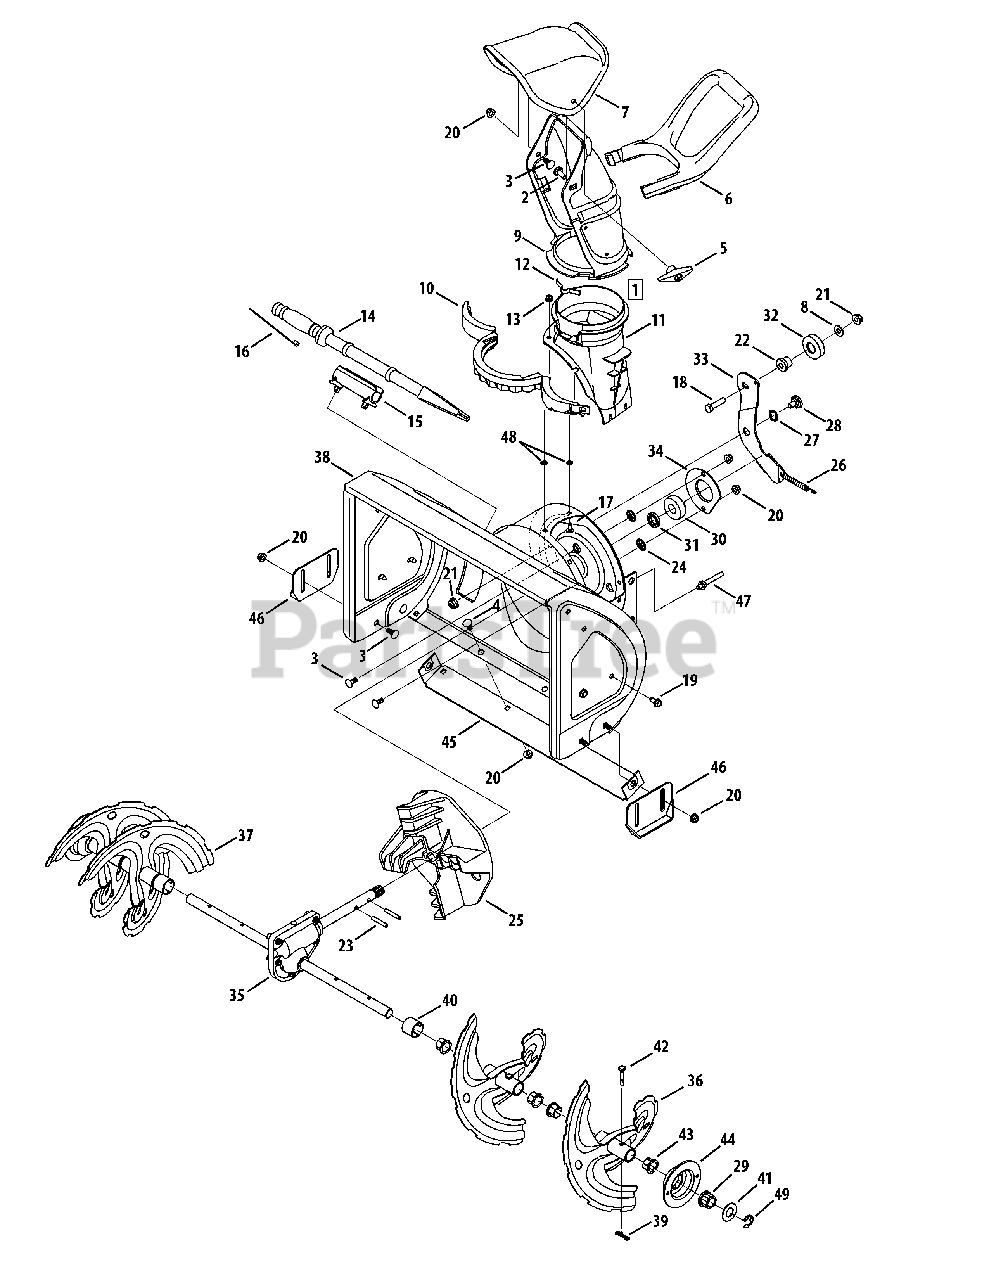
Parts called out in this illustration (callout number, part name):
1	Chute Assembly
2	Carriage Bolt 5/16-18 x 1.0"
3	Carriage Bolt 5/16-18
4	Carriage Bolt 5/16-18 x .62
5	Wing Knob 5/16-18
6	Chute Handle
7	Upper Chute
8	Flat Washer .385 x .87 x .06
9	Lower Chute
10	Chute Ring
11	Chute Adapter 5" Dia.
12	Chute Adjustment Spring
13	Flange Lock Nut 1/4-20
14	Clean-out Tool
15	Clean-out Tool Mount
16	Cable Tie
17	Carriage Screw 1/4-20 x 0.62"
18	Hex Bolt 3/8-16 x 1.50"
19	AB Screw 5/16-18 x .750
20	Flange Lock Nut, 5/16-18
21	Flange Lock Nut, 3/8-16
22	Shoulder Spacer
23	Spiral Pin
24	Push On Nut
25	Impeller
26	Extension Spring
27	Wave Washer
28	Shoulder Screw 3/8-16
29	Hex Flange Bearing
30	Ball Bearing
31	Spacer
32	Flat Idler
33	Auger Idler Bracket
34	Bearing Housing
35	Auger Gearbox Assembly
36	Auger Assembly - LH
37	Auger Assembly - RH
38	Auger Housing, 22" Red
39	Bow Tie Cotter Pin 72
40	Spacer, 1.25 x.75 x 1.00
41	Flat Washer, .76 x 1.49 x .06
42	Shear Pin,.25 x 1.50
43	Flange Bushing
45	Shave Plate 2.25 x 21.66 LG Red
46	Skid Shoe
47	Belt Keeper
48	Push Nut
49	E-Ring, .750
